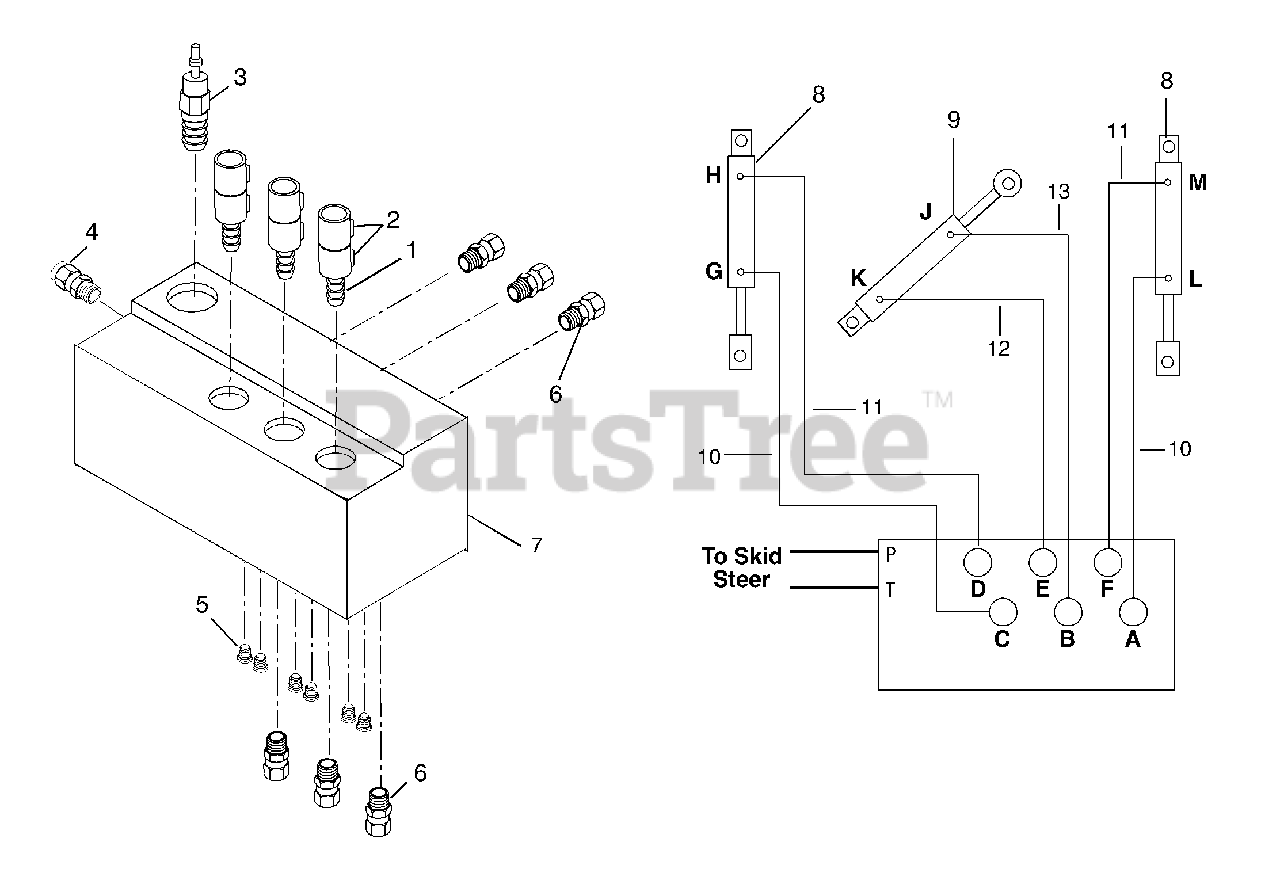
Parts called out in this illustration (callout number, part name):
1	4-Way Cartridge - 10 size
2	Leadwire Coil w/ Connector
3	Compensator Cartridge
4	Flow Control Cartridge
5	Sense Check
6	P.O. Check Cartridge
7	Hydraulic Valve
8	Cylinder 16"
9	Cylinder 8" Blade Pitch
10	Hydraulic Hose Leveling .250 X 24.5"
11	Hydraulic Hose Leveling .250 X 15.5"
12	Hydraulic Hose Blade Pivot .250 X 44.5"
13	Hydraulic Hose Pivot .250 X 49.5"
